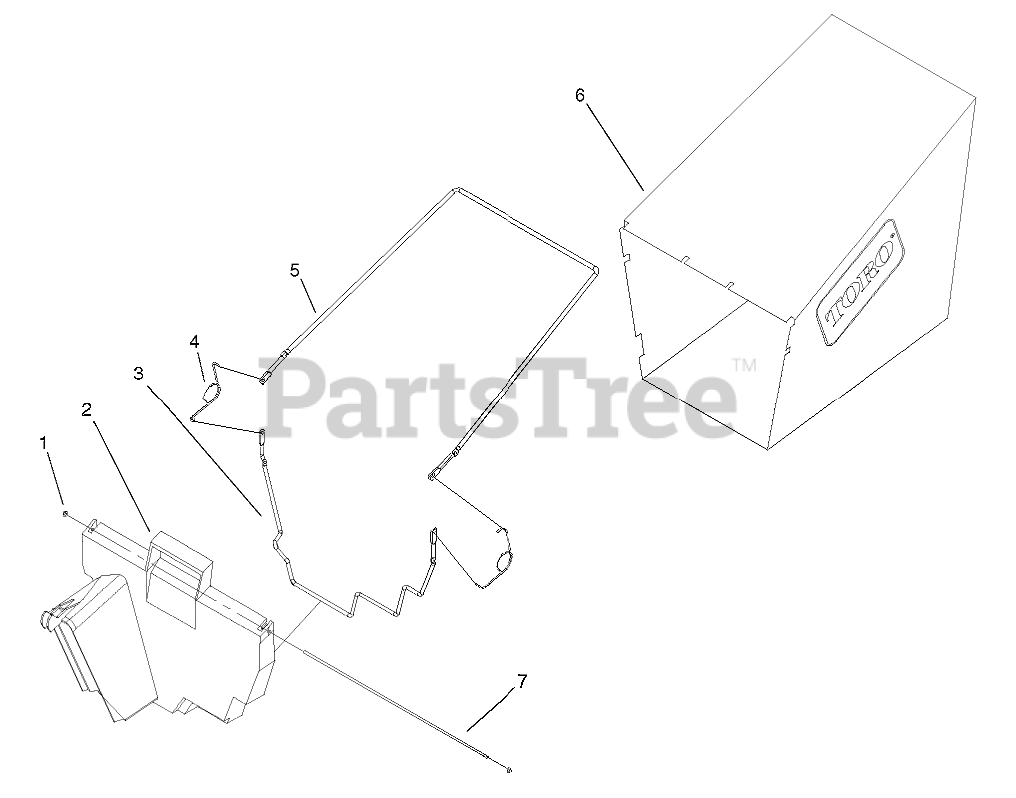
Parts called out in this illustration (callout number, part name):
1	NUT-PUSH
2	DOOR-BAG
3	FRAME-BAG
4	SPRING
5	FRAME-BAG, UPPER
6	Bag-Grass
7	HINGE-DOOR, BAG
